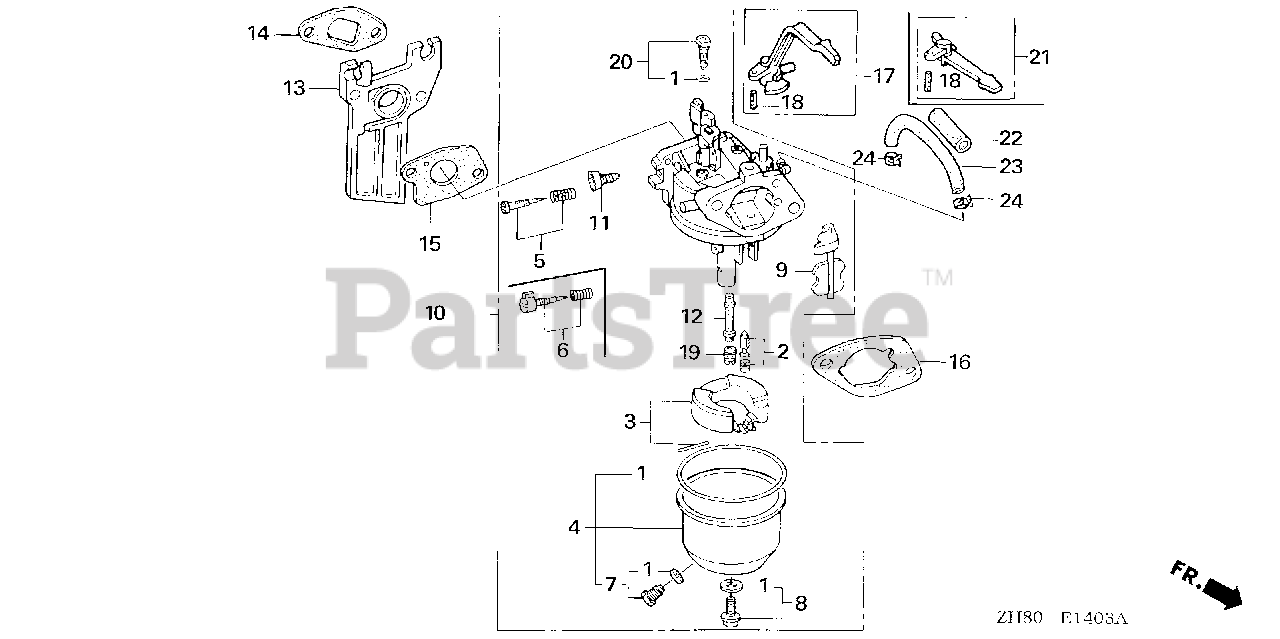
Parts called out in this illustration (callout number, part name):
1	GASKET SET
2	VALVE SET, FLOAT (SEAT NOT INCLUDED)
4	CHAMBER SET, FLOAT (CARBURETOR NO.)
6	SCREW SET, PILOT (CARBURETOR NO.)
7	SCREW SET, DRAIN (CARBURETOR NO.)
8	SCREW SET
10	CARBURETOR ASSY. (BE67A B)
11	SCREW, THROTTLE STOP
12	NOZZLE, MAIN (CARBURETOR NO.)
13	INSULATOR, CARBURETOR
14	GASKET, INSULATOR
15	GASKET, CARBURETOR
16	GASKET, AIR CLEANER
17	LEVER, CHOKE
18	PIN, SPRING (2X12)
19	JET, MAIN (#72) (CARBURETOR NO.)
19	JET, MAIN (#75) (CARBURETOR NO.)
19	JET, MAIN (#70)
20	JET SET, PILOT (#35) (CARBURETOR NO.)
